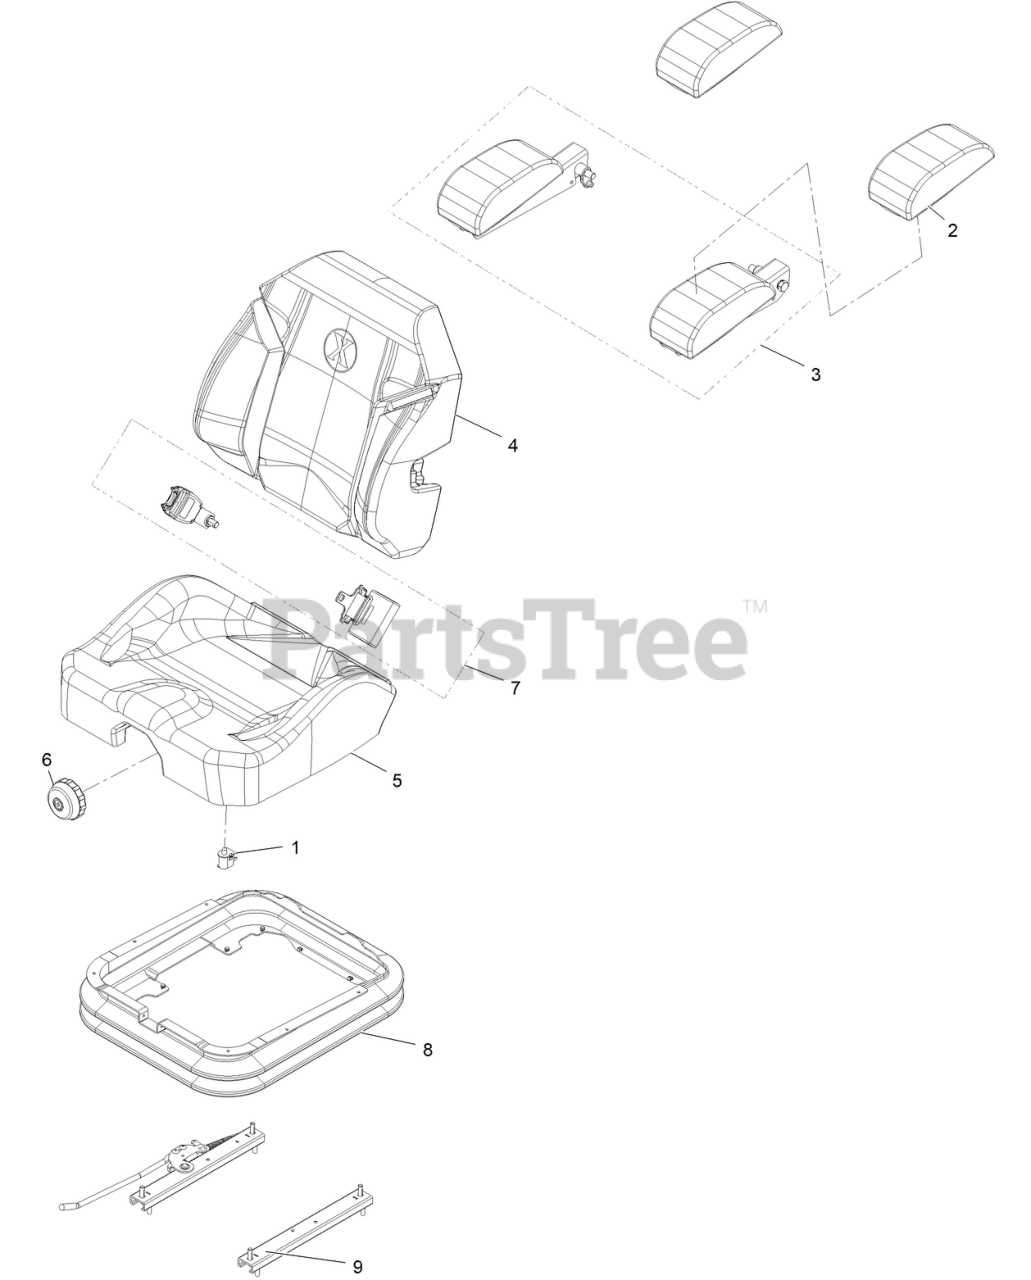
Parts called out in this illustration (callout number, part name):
1	SWITCH-BAIL
2	KIT-ARM REST PADS
3	KIT-ARM REST SET
4	COVER-BACK 311463VN500
5	COVER-CUSHION
6	KNOB-ADJUSTER
7	KIT-SEAT BELT
8	COVER-SUSPENSION BELLOWS
9	SET-SEAT TRACK
